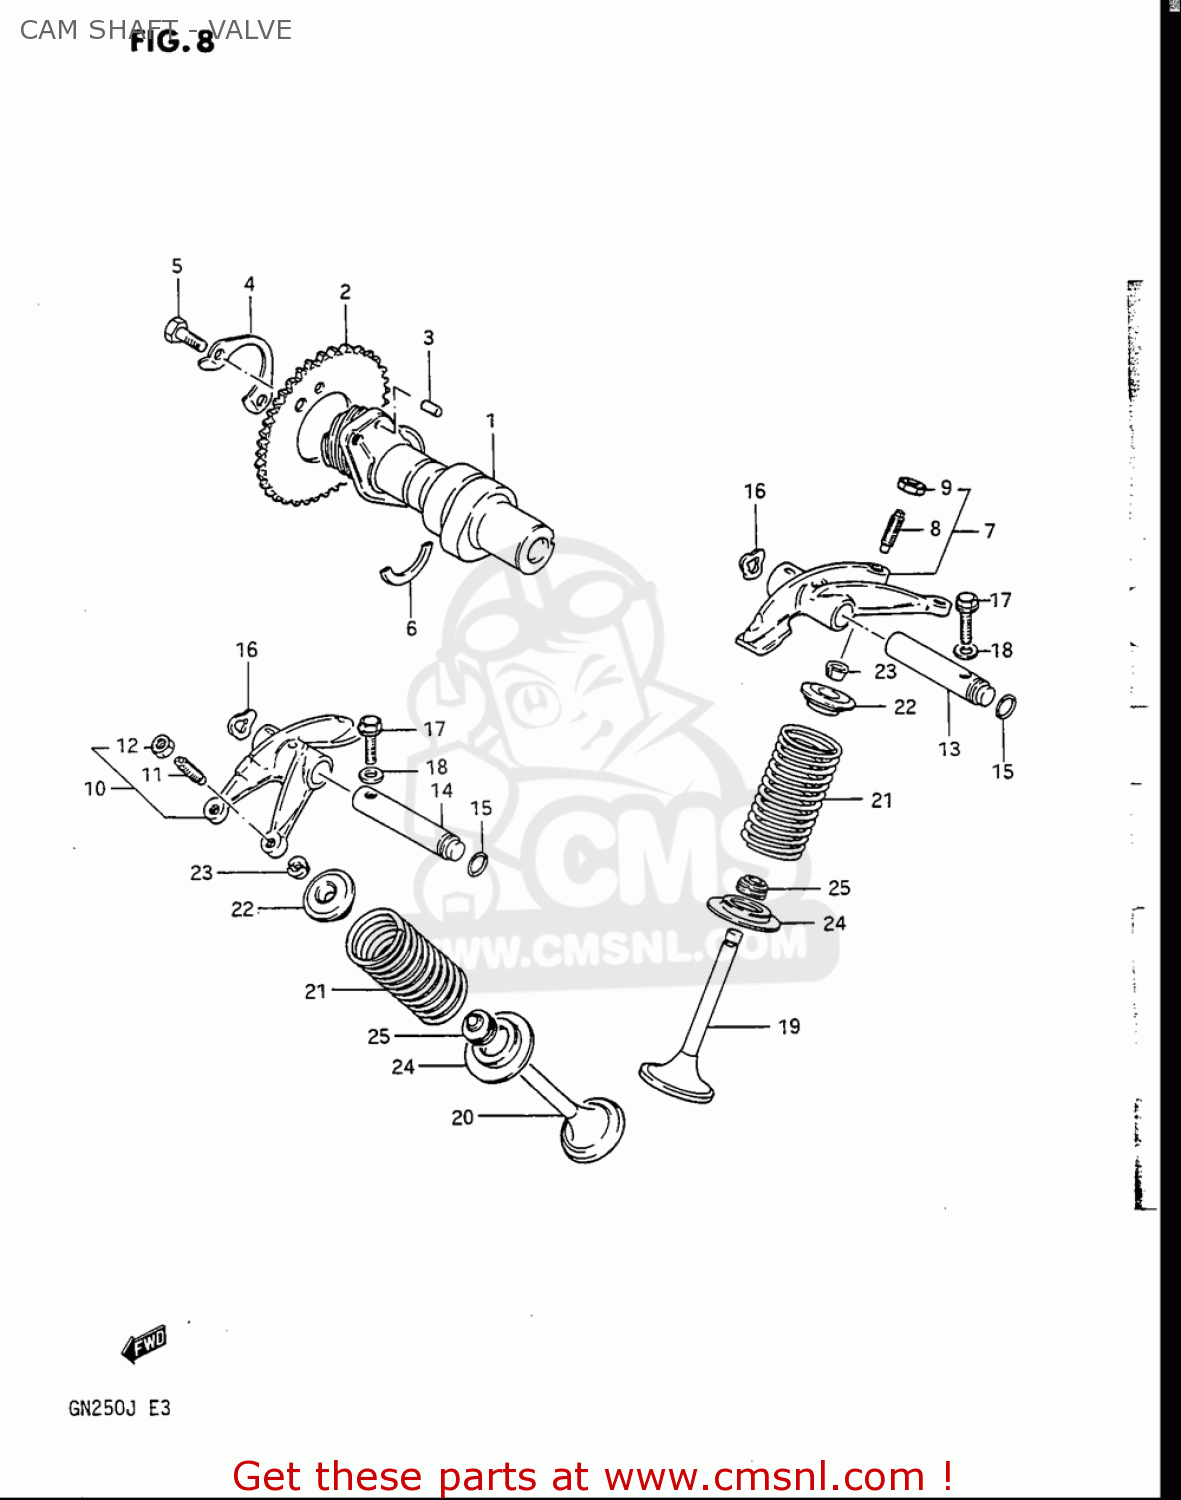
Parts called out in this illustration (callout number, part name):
1	CAMSHAFT
2	SPROCKET,CAMSHAFT(NT:42)
3	PIN
4	WASHER,CAM CHAIN SPROCKET
5	BOLT(6X12.5)
6	C RING
7	ARM,VALVE ROCKER INTAKE
8	SCREW,TAPPET ADJUSTING
9	NUT,TAPPET ADJUSTING
10	ARM,VALVE ROCKER EXHAUST
11	SCREW,TAPPET ADJUSTING
12	NUT,TAPPET ADJUSTING
13	SHAFT,VLV ROCKER ARM IN(L:91.5
14	SHAFT,VLV ROCKER ARM EXH(L:76)
15	O RING(D:1.9,ID:8.6)
16	WASHER
17	BOLT
18	GASKET(5.8X13X1.2) (NAS)
19	VALVE,INTAKE
20	VALVE,EXHAUST
21	SPRING,VALVE
22	RETAINER,VALVE SPRING
23	COTTER VALVE
24	SEAT,VALVE SPRING
25	SEAL,OIL(5.5X11X8.2)
